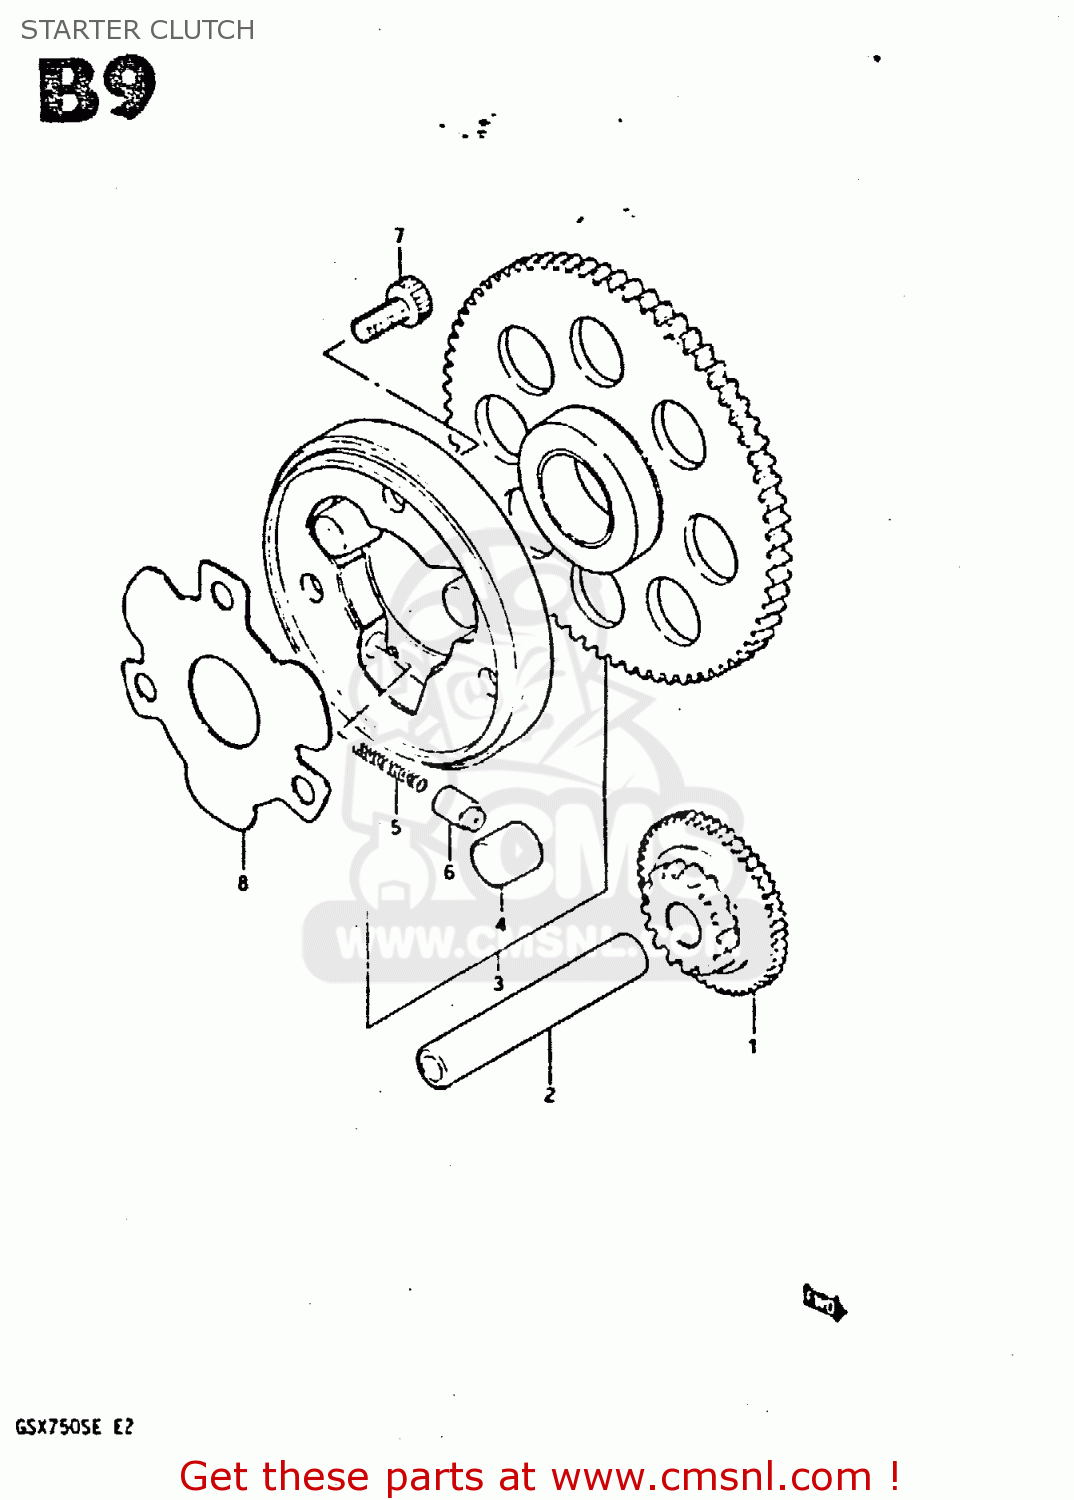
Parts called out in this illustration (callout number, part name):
1	GEAR,STARTER IDLE
2	PIN(7.4X13X56)
3	CLUTCH SET,STARTER
4	PIN(14X13)
5	SPRING
6	PIECE,PUSH
7	BOLT
8	SHIM,STARTER CLUTCH HUB
